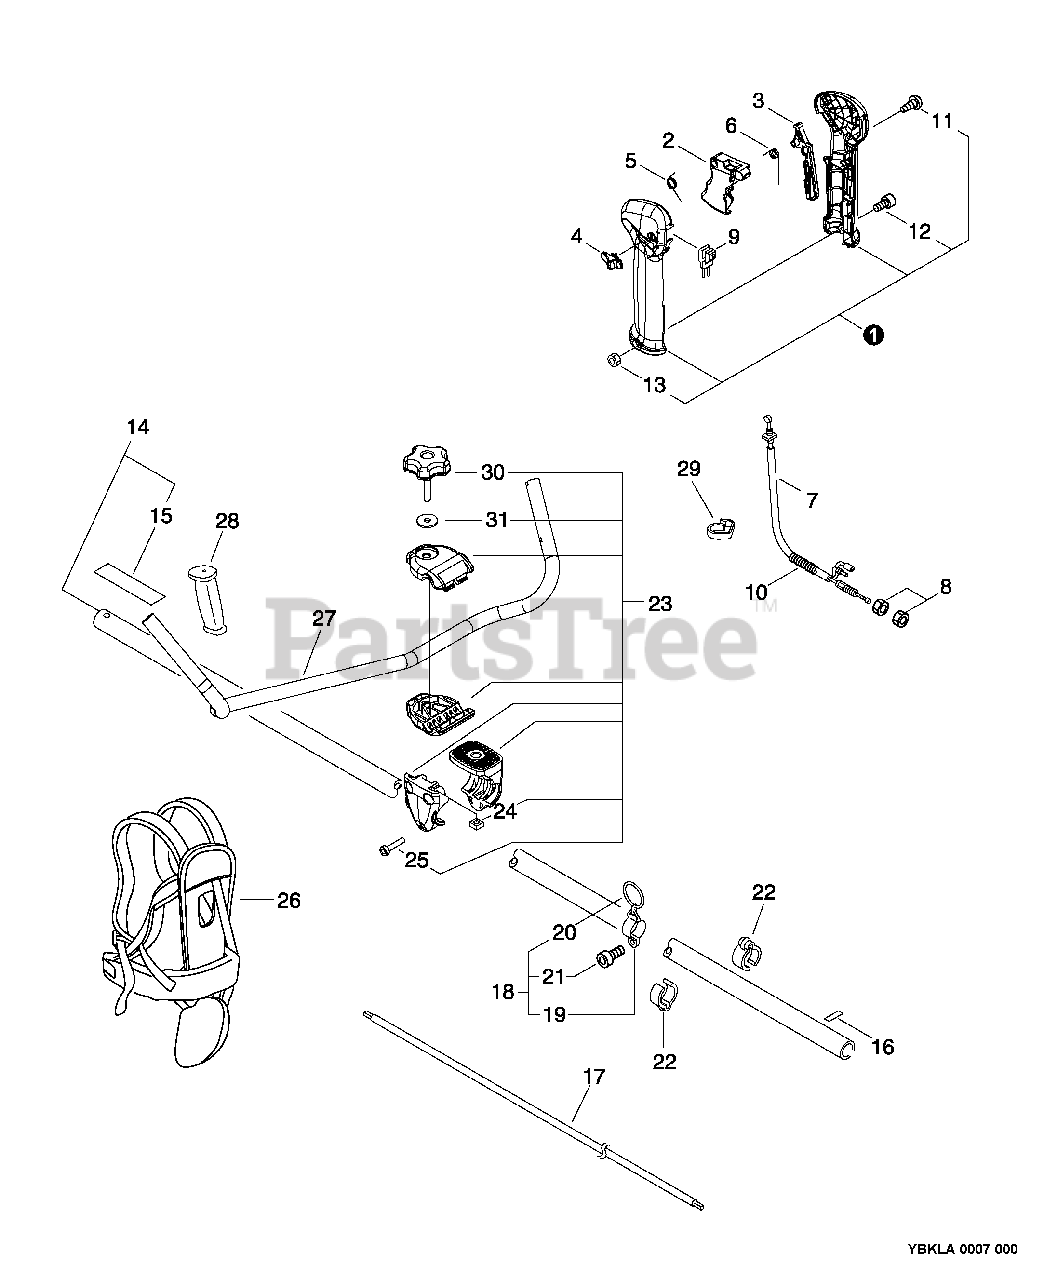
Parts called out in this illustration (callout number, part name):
1	THROTTLE CONTROL ASSY
2	TRIGGER, THROTTLE
3	LOCKOUT, THROTTLE
5	SPRING, TORSION
6	SPRING, TORSION
7	CABLE, THROTTLE
9	SWITCH, ON-OFF
11	SCREW 4×16
13	NUT M5
14	MAIN PIPE ASSY
15	LABEL, CAUTION - ISO
16	LABEL - ALIGNMENT
17	DRIVESHAFT
18	HANGER ASSY, HARNESS
19	HANGER, HARNESS
20	RING, HARNESS
21	BOLT 5×12
22	CLIP 28 MM
23	MOUNTING KIT, HANDLEBAR
24	NUT 8×1.25
25	BOLT 5×30
26	HARNESS, BRUSHCUTTER
27	HANDLEBAR
28	GRIP, HANDLE
30	KNOB, SCREW M8
31	WASHER 8
